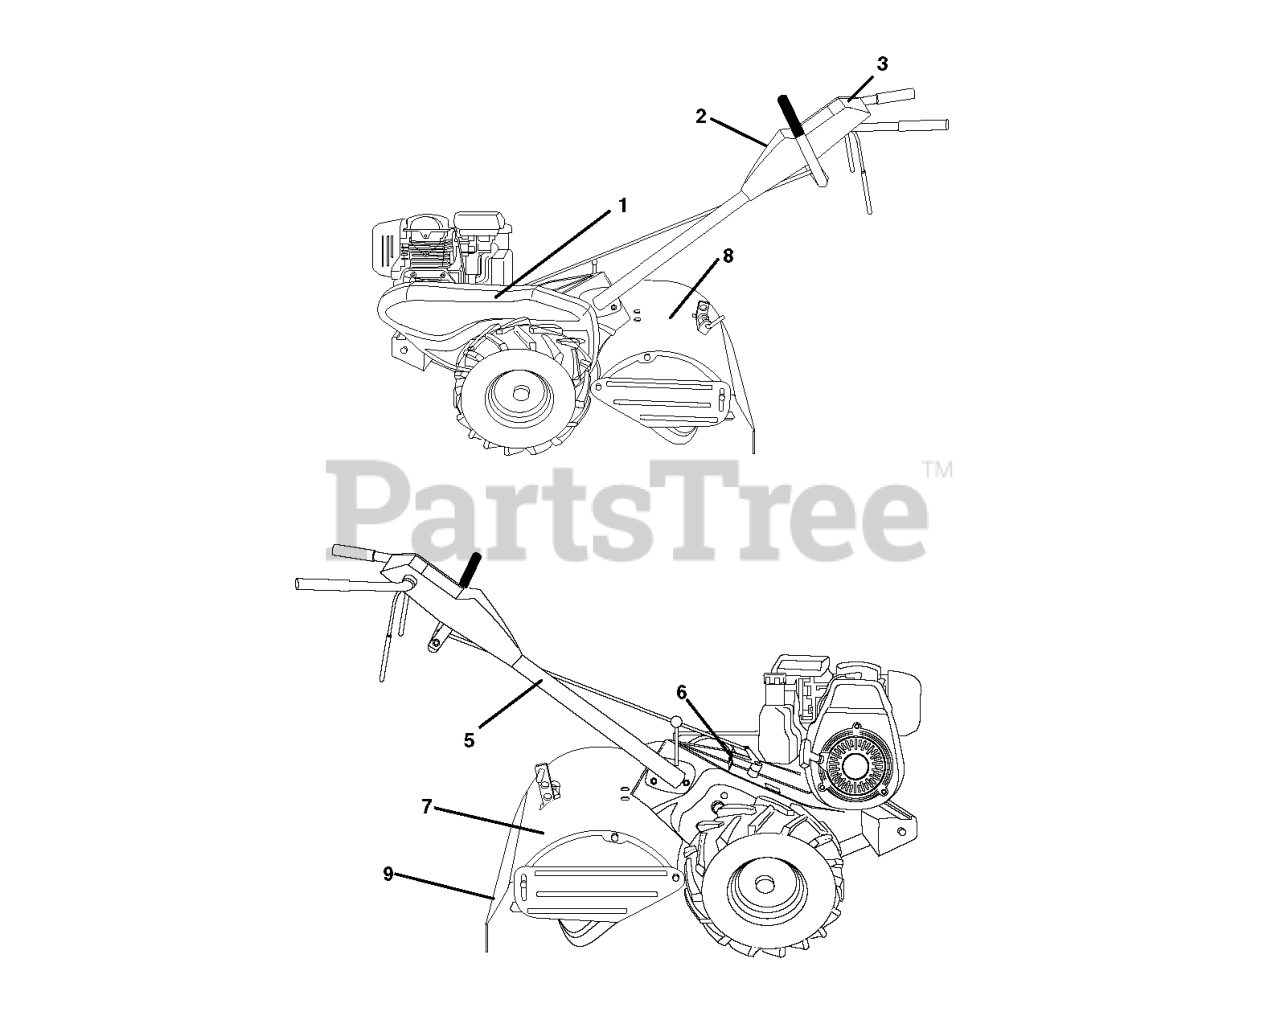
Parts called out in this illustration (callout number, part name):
2	DECAL, LOGO
3	DECAL, CONTROL PNL
5	DECAL TI (2 2)
6	DECAL.SHIFT.INDICATOR.TILLER
7	DECAL -CAUTION
8	DECAL, TINESHEILD
9	DECAL TI
